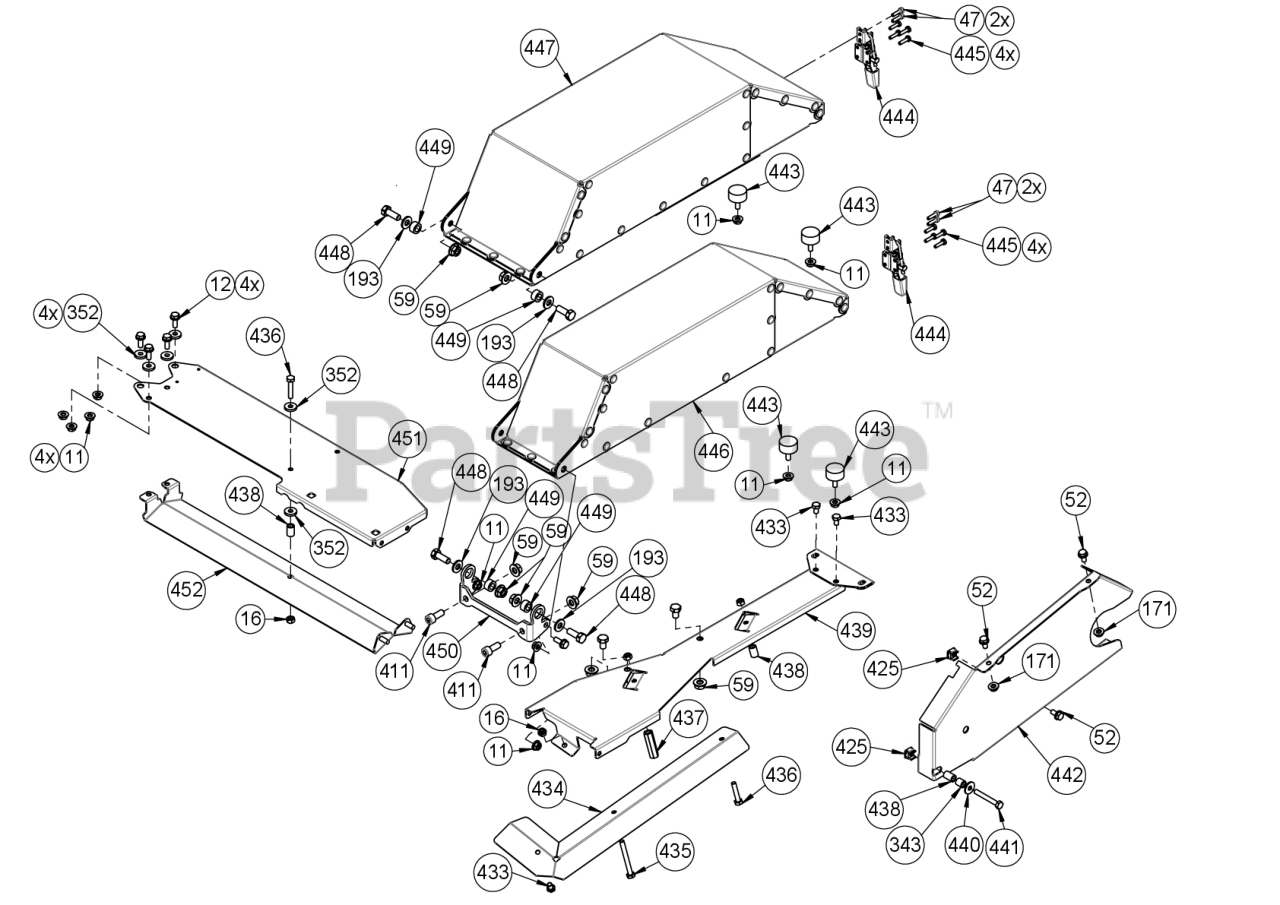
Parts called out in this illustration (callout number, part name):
11	NUT, FLG SLF LK M6 CL 8 ZCC
12	NUT, FLG SLF LK M6X16
16	NUT, LK V-M6 DIN 980 8 ZCC
47	SCR, SKH M4X16 DIN ISO 4762 8.8
52	BLT, FLG M6X12 DIN 6921 8.8 ZCC
59	NUT, FLG SLF LK M8 CL 8 ZCC
171	NUT, FLG M6 DIN 6923 8 ZCC
193	WSHR, FLT M8.4 DIN 134 ZCC
352	WSHR, FLT M6.4 DIN 7349 ST ZCC
411	SCR, SKH. M8X20 DIN ISO 4762 8.8 ZCC
425	NUT, CAGE M6
433	BLT, HEX M6X10 DIN 933 8.8 ZCC
434	SHIELD, MANIFOLD
435	BLT, HEX M6X55 DIN 931 8.8 ZCC
436	BLT, HEX M6X30 DIN 933 8.8 ZCC
437	NUT, COUPLING M8X40
439	BRACKET, HOOD
440	WSHR, FLT M6.4 DIN 9021
441	BLT, HEX M6X45 DIN 931 8.8 ZCC
442	BELT COVER, PRIMARY
443	BUMPER, RUBBER
444	HOOD LATCH
445	SCR, TAP M4X16 TORX T20 ZCC
446	HOOD, VENTED RIGHT
447	HOOD, VENTED LEFT
448	BLT. HEX M8X22 DIN 933 8.8 ZCC
450	BRACKET, HOOD HINGE
451	PLATE, CROSS
452	SHIELD, MUFFLER
